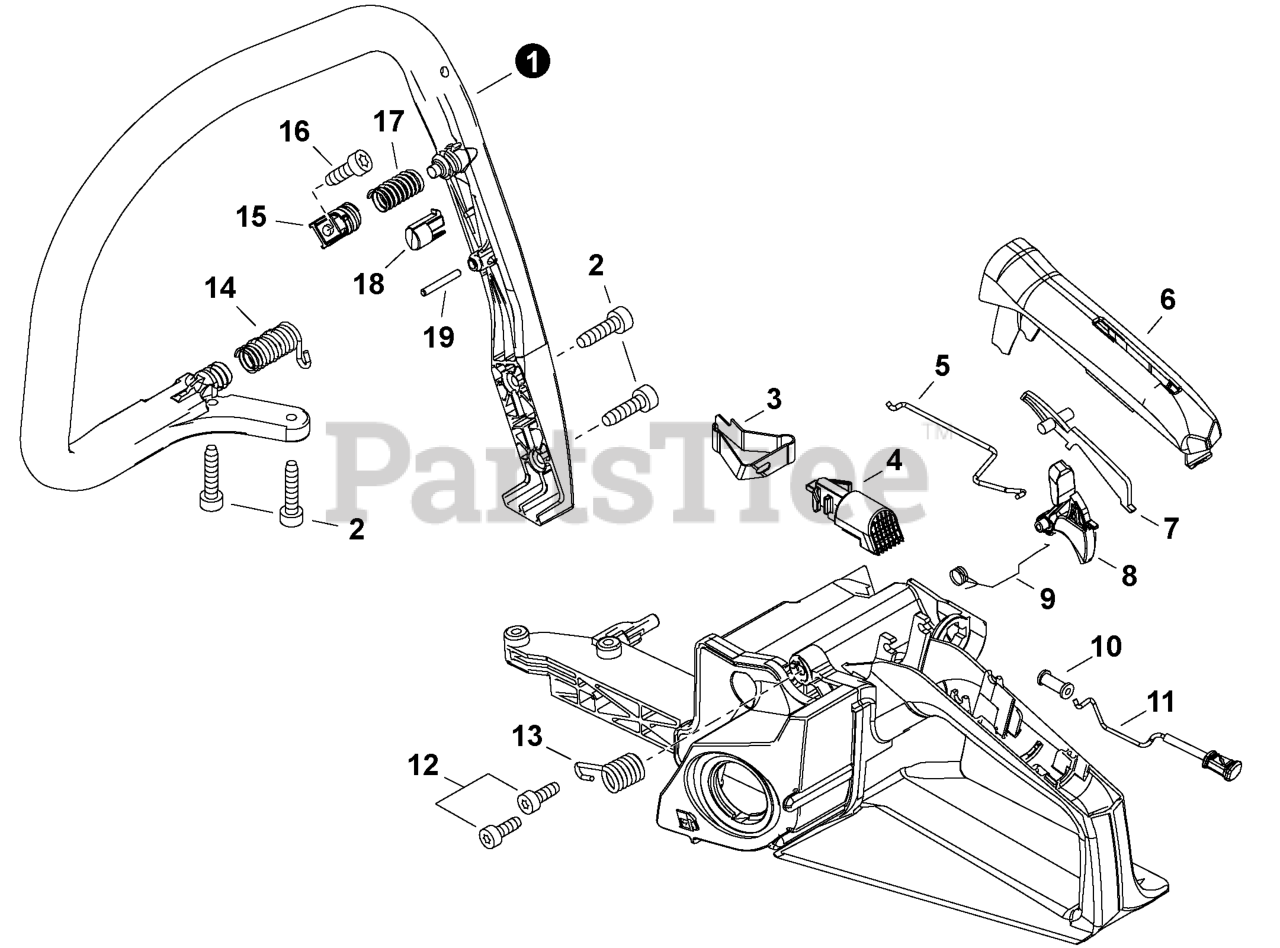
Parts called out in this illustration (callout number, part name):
1	HANDLE, FRONT
2	BOLT, TORX 5x20
3	TERMINAL, LEAD
4	SWITCH, STOP
5	ROD, THROTTLE
6	COVER, HANDLE
7	LEVER, THROTTLE LOCKOUT
8	TRIGGER, THROTTLE
9	SPRING, TORSION
10	GROMMET, CHOKE
11	KNOB, CHOKE
12	BOLT, TORX 5x12
13	SPRING, COMPRESSION
14	SPRING, COMPRESSION
15	HOLDER, SPRING
16	BOLT, TORX 5x12
17	SPRING, COMPRESSION
18	CUSHION
